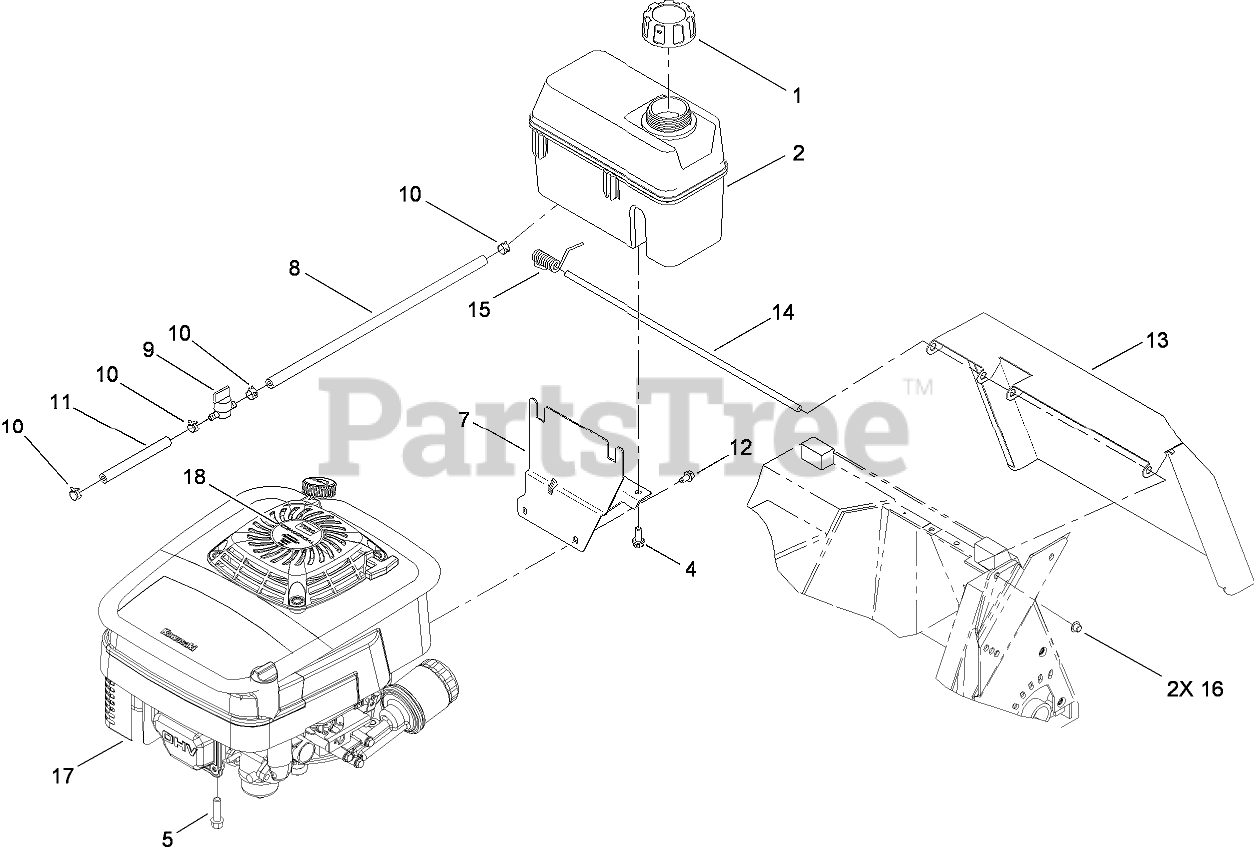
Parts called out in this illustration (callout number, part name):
1	CAP-GAS
2	Tank-Fuel
4	SCREW-HWH
5	SCREW-TAPTITE
7	MOUNT-TANK
8	HOSE-FUEL
9	VALVE-FUEL
10	CLAMP-HOSE
11	HOSE-FUEL
12	SCREW-HWH
13	DOOR-DISCHARGE, REAR
14	ROD-DOOR
15	SPRING-TORSION, DOOR
16	PUSHNUT-CAP, WASHER
17	ENGINE ASM
